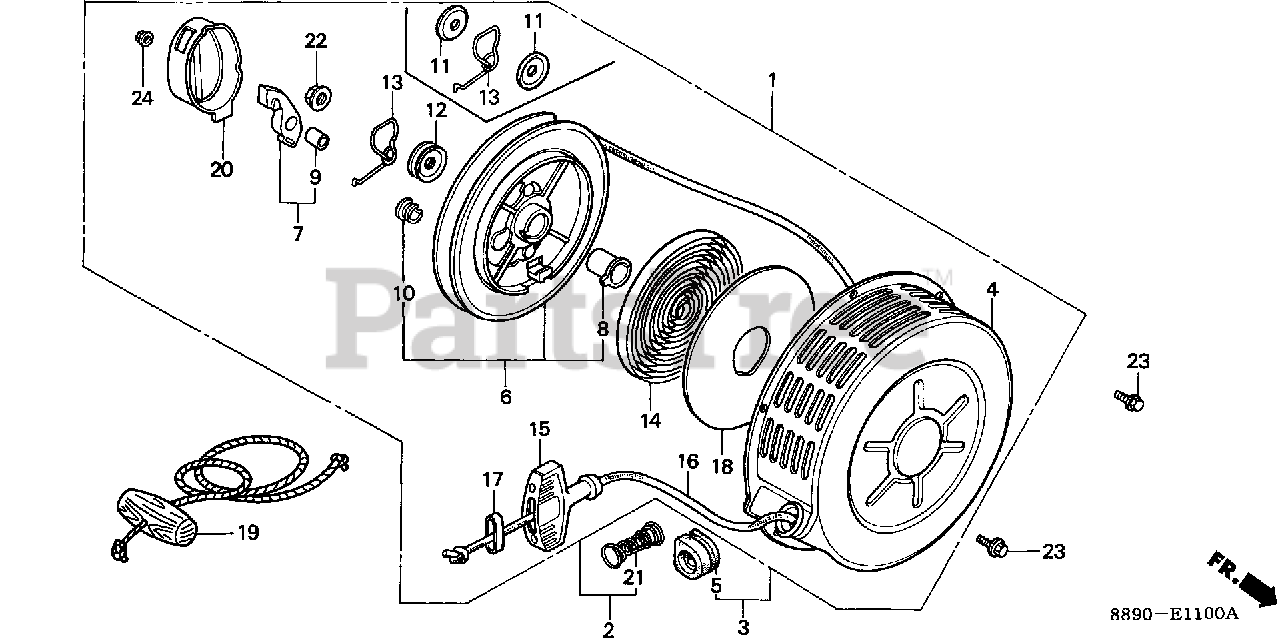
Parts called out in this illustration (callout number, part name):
1	STARTER ASSY., RECOIL *R280* (POWER RED)
2	STARTER ASSY., RECOIL *R8* (BRIGHT RED) (NOT AVAILABLE)
4	CASE, STARTER *R8* (BRIGHT RED)
6	REEL, STARTER
8	BOSS, REEL
9	BUSH, RATCHET
10	BUSH, REEL STARTER
12	PLATE, FRICTION
13	SPRING, FRICTION
14	SPRING, RETURN
15	GRIP, STARTER
16	ROPE, RECOIL STARTER
17	SUPPORT, GRIP
18	PLATE, SIDE (NOT AVAILABLE)
19	ROPE, STARTER
20	COVER, STARTER REEL
21	SPRING, ROPE GUIDE
22	NUT, SELF-LOCK (8MM) (CLINCH)
23	BOLT, FLANGE (6X8)
24	NUT, FLANGE (5MM)
